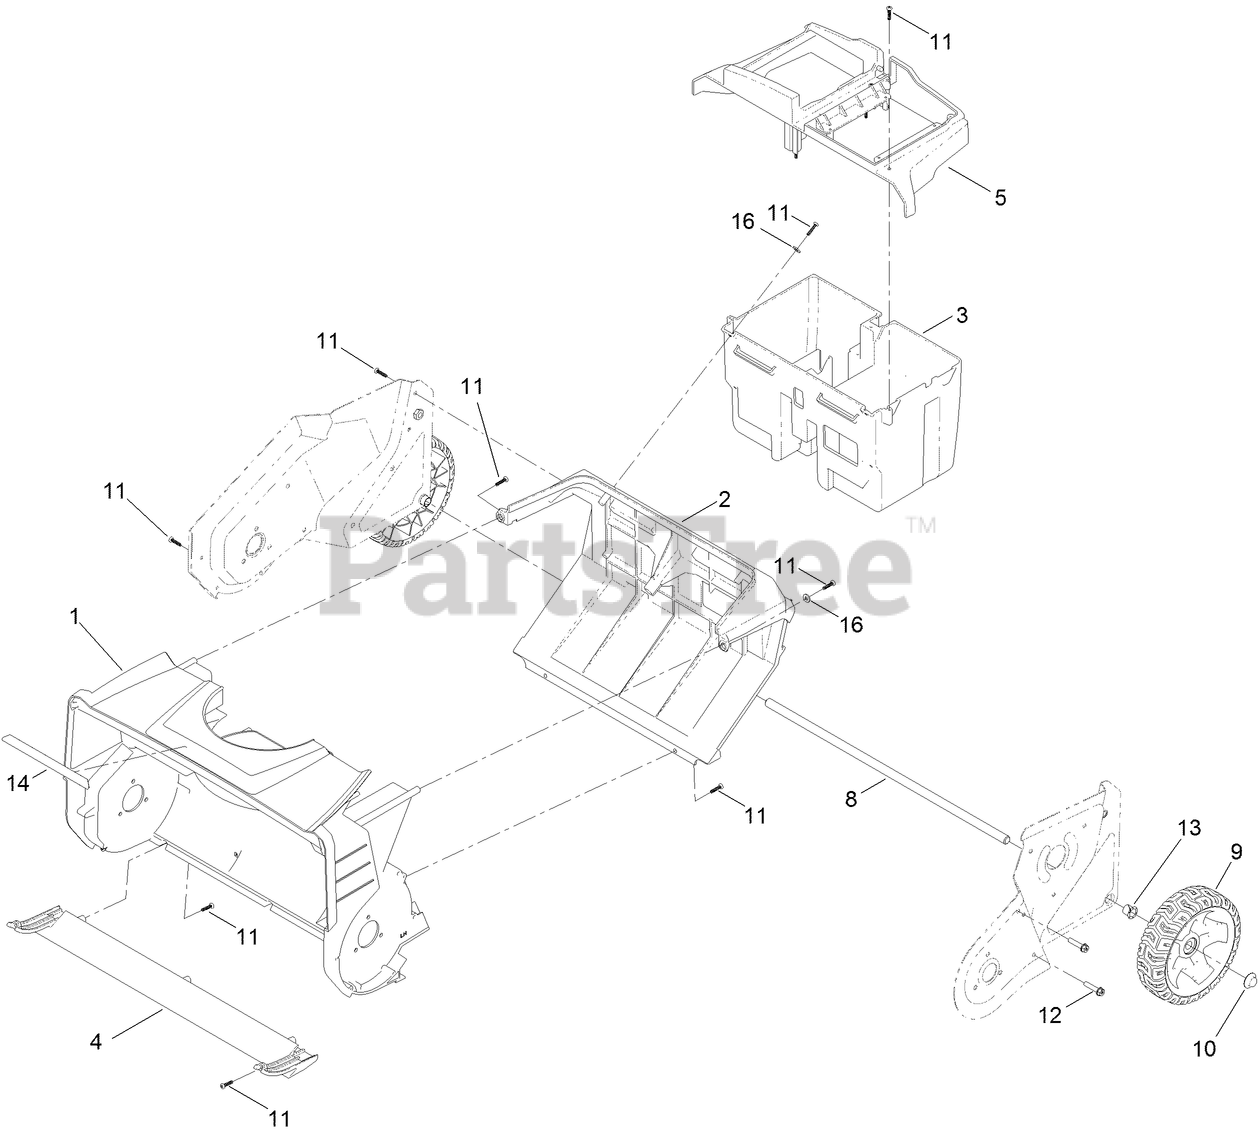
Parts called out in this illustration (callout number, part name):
1	HOUSING
2	BULKHEAD
3	CONTAINER-BATTERY
4	SCRAPER
5	SKIRT-CONTAINER, BATTERY
9	WHEEL ASM
10	NUT-PUSH
11	SCREW-PPH
12	SCREW-PLASTIC
13	BUSHING-NYLINER
14	DECAL-POWER EDGE
16	WASHER-FLAT
